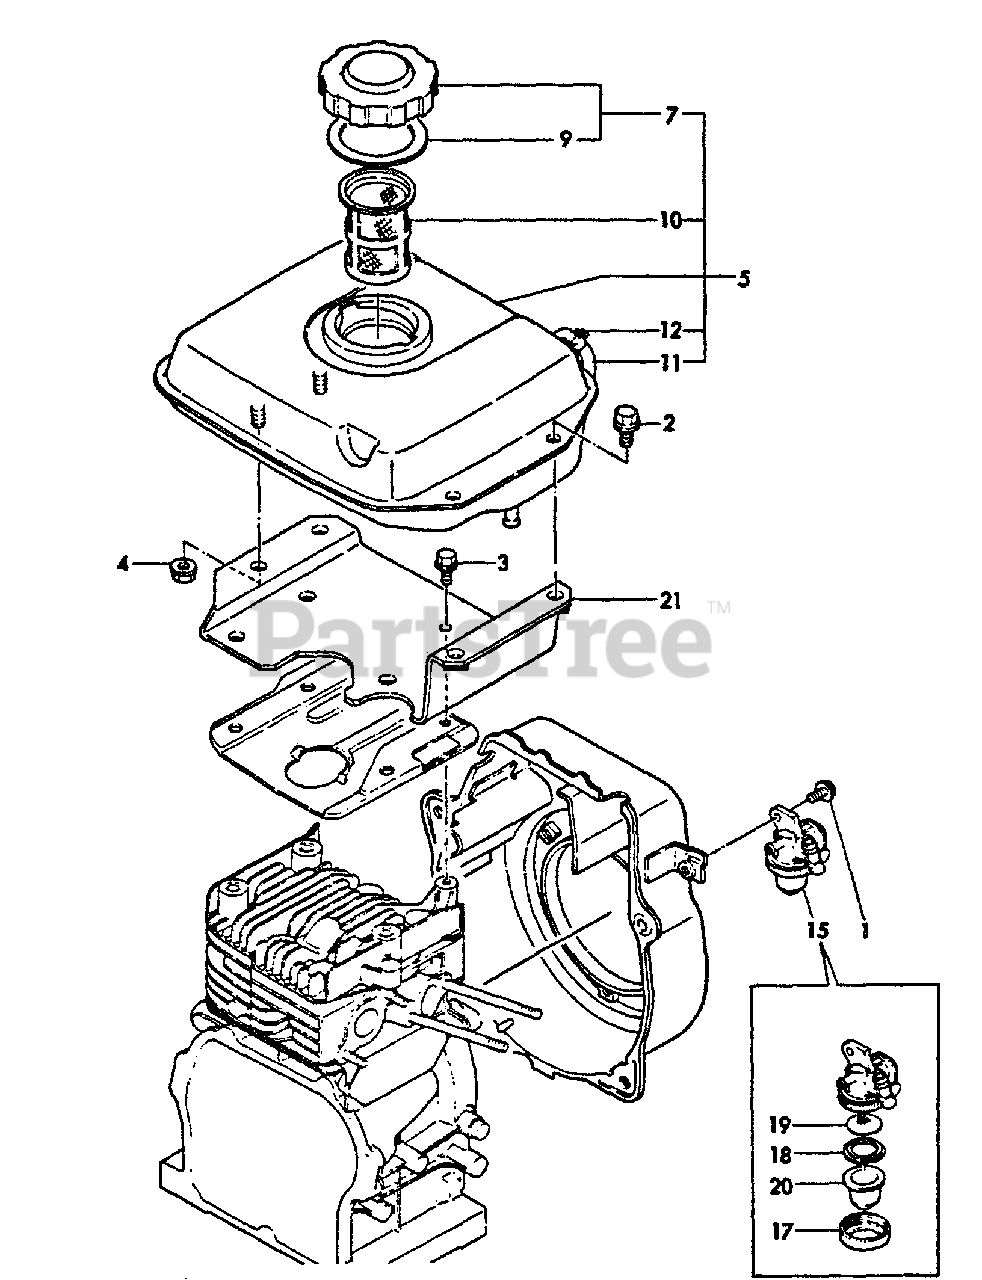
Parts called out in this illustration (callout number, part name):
1	BOLT - 6×12 -- PLATED
2	BOLT - 8×14 -- PLATED
3	BOLT - 6×8 -- PLATED
4	U-NUT M8
5	FUEL TANK ASSY
7	CAP ASSY
9	GASKET
10	STRAINER, FUEL
11	GAUGE, LEVEL
12	CLAMP, HOSE - 9
15	COCK ASSY, FUEL
17	RETAINER
18	GASKET
19	FILTER, FUEL
20	BOWL, STRAINER
21	BRACKET, FUEL TANK
